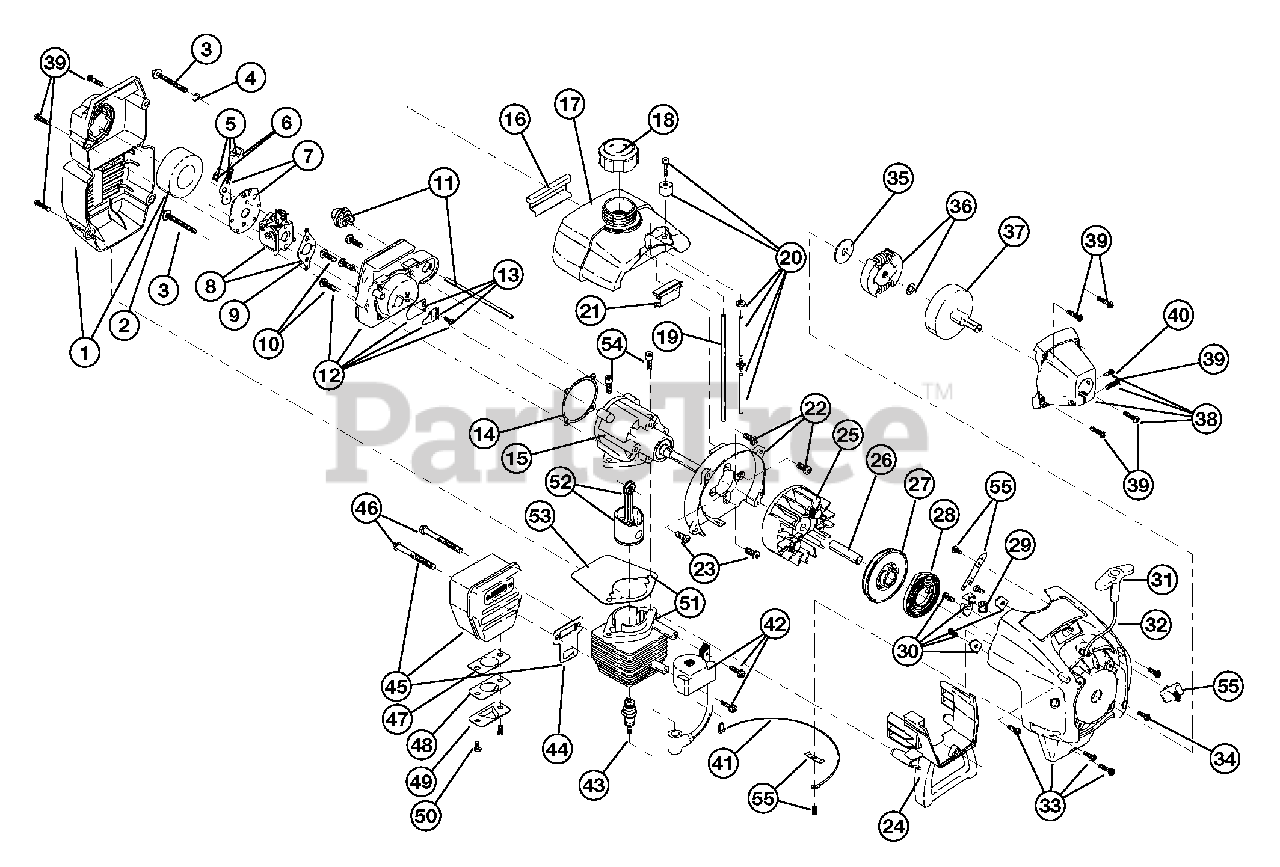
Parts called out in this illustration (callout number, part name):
1	Air Cleaner/Muffler Cover Assembly
2	Air Cleaner Filter
3	Carburetor Mounting Screw Assembly
4	Wavey Washer
5	Choke Lever Assembly
6	Choke Knob and Screw
7	Choke Lever and Plate
8	Carburetor Assembly
9	Carburetor Gasket
10	Carb Mount Screw
11	Primer and Hose Assembly
12	Carb Mount Assembly
13	Reed Assembly
14	Carburetor Mount Gasket
15	Crank Case Service Assembly
16	Rear Mounting Pad
17	Fuel Tank Assembly
18	Fuel Cap Assembly
19	Fuel Return Line
20	Fuel Line Assembly
21	Front Mounting Pad
22	Shroud Assembly
23	Shroud Screw
24	Shroud Extension & Stand
25	Flywheel Assembly
27	Recoil Pulley Assembly
28	Recoil Spring
29	Rope Guide
30	Pulley Retainer Assembly
31	Pull Handle
33	Starter Housing Assembly
34	Housing Screw
35	Clutch Washer
36	Clutch Rotor Assembly
37	Clutch Drum Assembly
38	Clutch Cover Assembly
39	Cover Screw
40	Anti-Rotation Screw
41	Wire Lead
42	Module Assembly
43	Spark Plug
44	Exhaust Gasket
45	Muffler Assembly
46	Muffler Mounting Bolts
47	Spark Arrestor Screen
48	Spark Arrestor Plate
49	Spark Arrestor Hood
50	Spark Arrestor Screws
51	Cylinder Assembly
52	Piston and Rod Assembly
53	Cylinder Gasket
54	Cylinder Bolt
55	Switch Assembly
